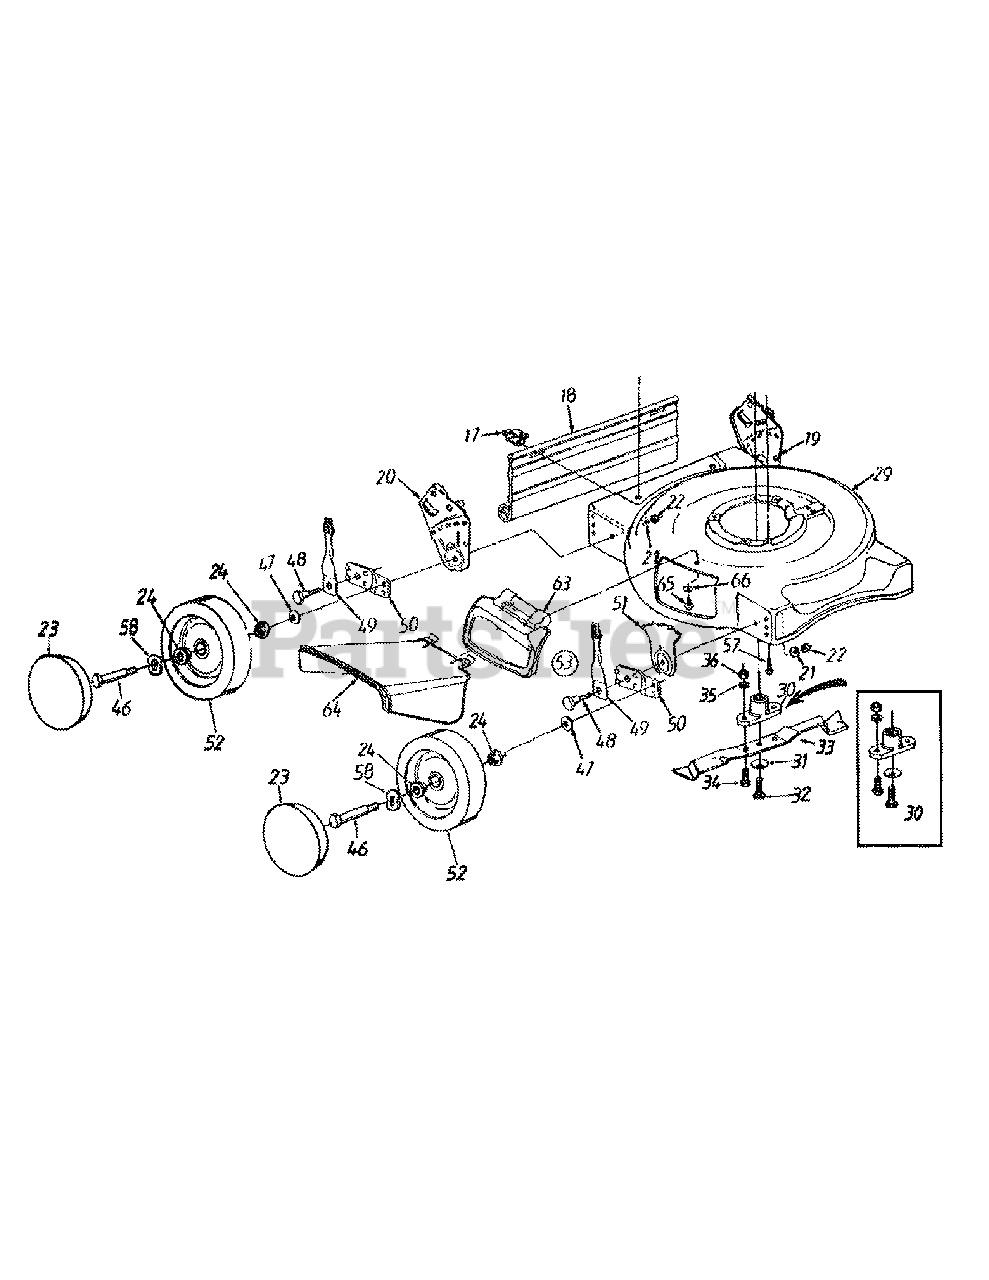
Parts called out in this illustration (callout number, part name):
17	Hinge Clip
18	Rear Flap (108R)
18	Rear Flap (702R)
19	Handle Bracket Ass'y.- L.H. (108R)
19	Handle Bracket Ass'y.- L.H. (702R)
20	Handle Bracket Ass'y.- R.H. (108R)
20	Handle Bracket Ass'y.- R.H. (702R)
21	Bell-Wash..39" I.D. x 1.38"
22	Hex Nut 3/8-16 Thd.
23	Hub Cap
24	Bearing
29	20" Deck Ass'y. (108R)
31	Bell-Wash..46" I.D.
32	Hex Bolt 7/16-20 x 1.5" Lg.
33	20" Mulching Blade (108R)
33	18" Mulching Blade (702R)
34	Hex Bolt 3/8-24 x 1" Lg.
35	L-Wash. 3/8" I.D.
36	Hex Nut 3/8-24 Thd.
46	Axle Bolt
47	Bell-Wash..400" I.D. x.88"
48	Shld. Bolt .50" Dia. x .357"
49	Spring Lever Ass'y. w/Knob
51	Height Adj. Plate
52	Wheel Ass'y. Comp.
53	Height Adj. Ass'y. Comp.- R.F. & L.R.
53	Height Adj. Ass'y. Comp.- L.F. & R.R.
57	Hex L-Wash. Hd. Scr. 3/8-16 x 1.0" Lg.
58	Wave Washer .51" I.D.
63	Mulching Plug (108R)
63	Mulching Plug (702R)
64	Chute Deflector
65	Bell-Wash. 1/4" I.D.
66	Hex Wash Hd. TT-Tap Scr. 1/4-20 x .5" Lg
